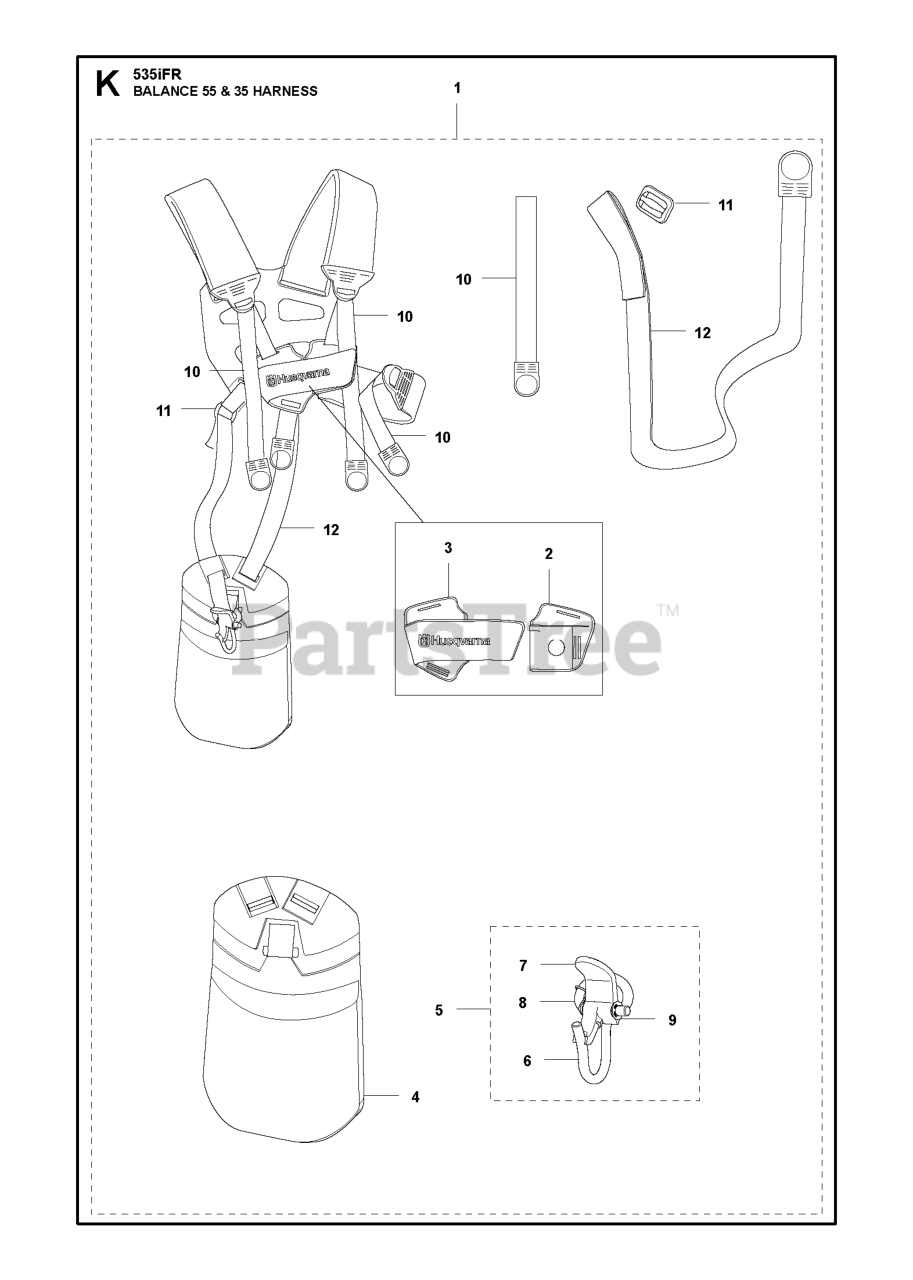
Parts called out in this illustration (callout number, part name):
1	Duo-Bal Harness
1	Duo Balance Harness
2	FRONT PIECE
3	FRONT PIECE
5	HARNESS HOOK, COMPLETE
6	HOOK
7	CATCH *
8	SPRING
